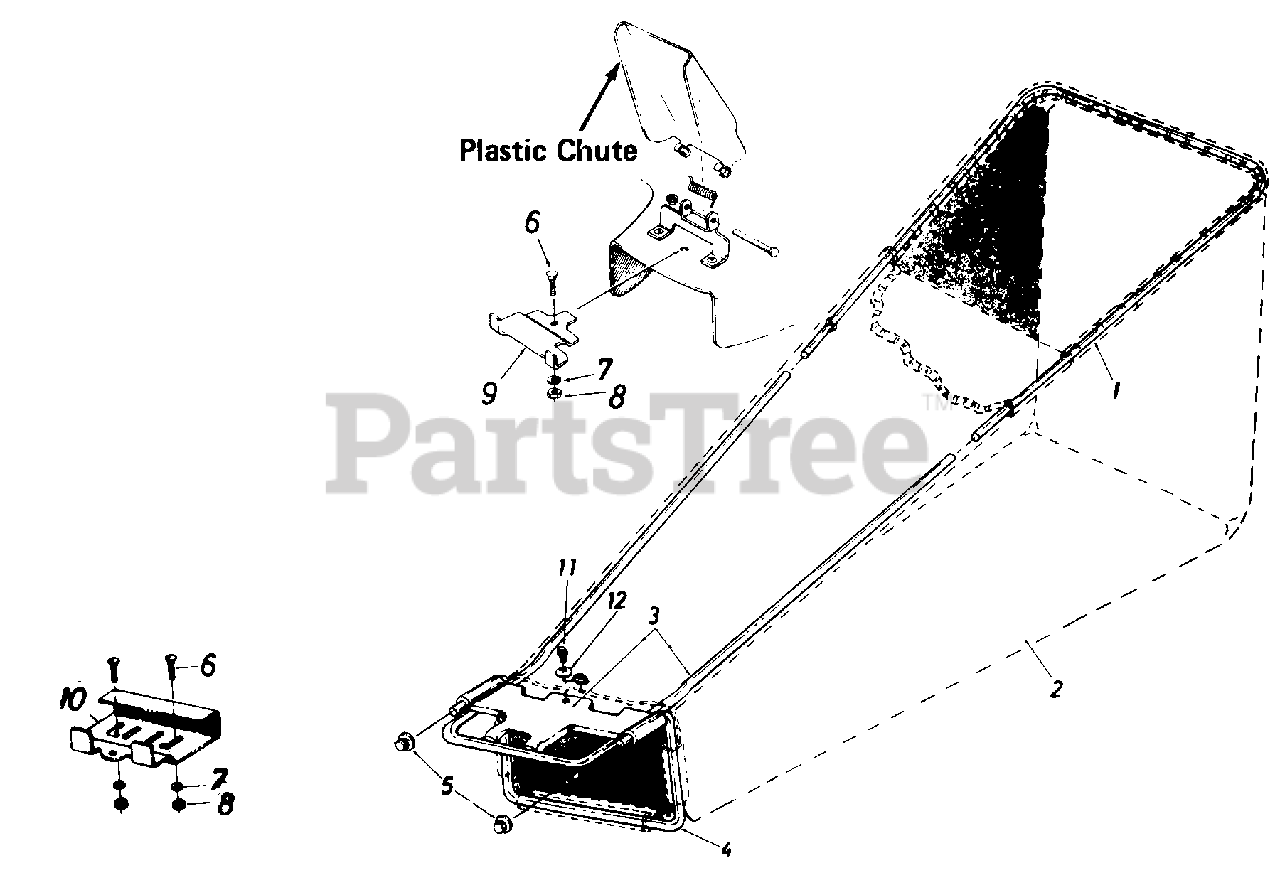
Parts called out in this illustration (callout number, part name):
1	Frame-Upper
2	Grass Catcher Bag
3	Frame-Lower
4	Lower Frame Rod
5	Push Cap
6	Carriage Bolt
7	LockWasher 1/4" I.D. *
8	Hex Nut 1/4-20 Thd.*
9	Adapter Plate
10	Adapter Plate
11	Self-Tap Scr. 1/4 x 1/2" Lg.
12	Bell-Wash. 1/4" I.D.
